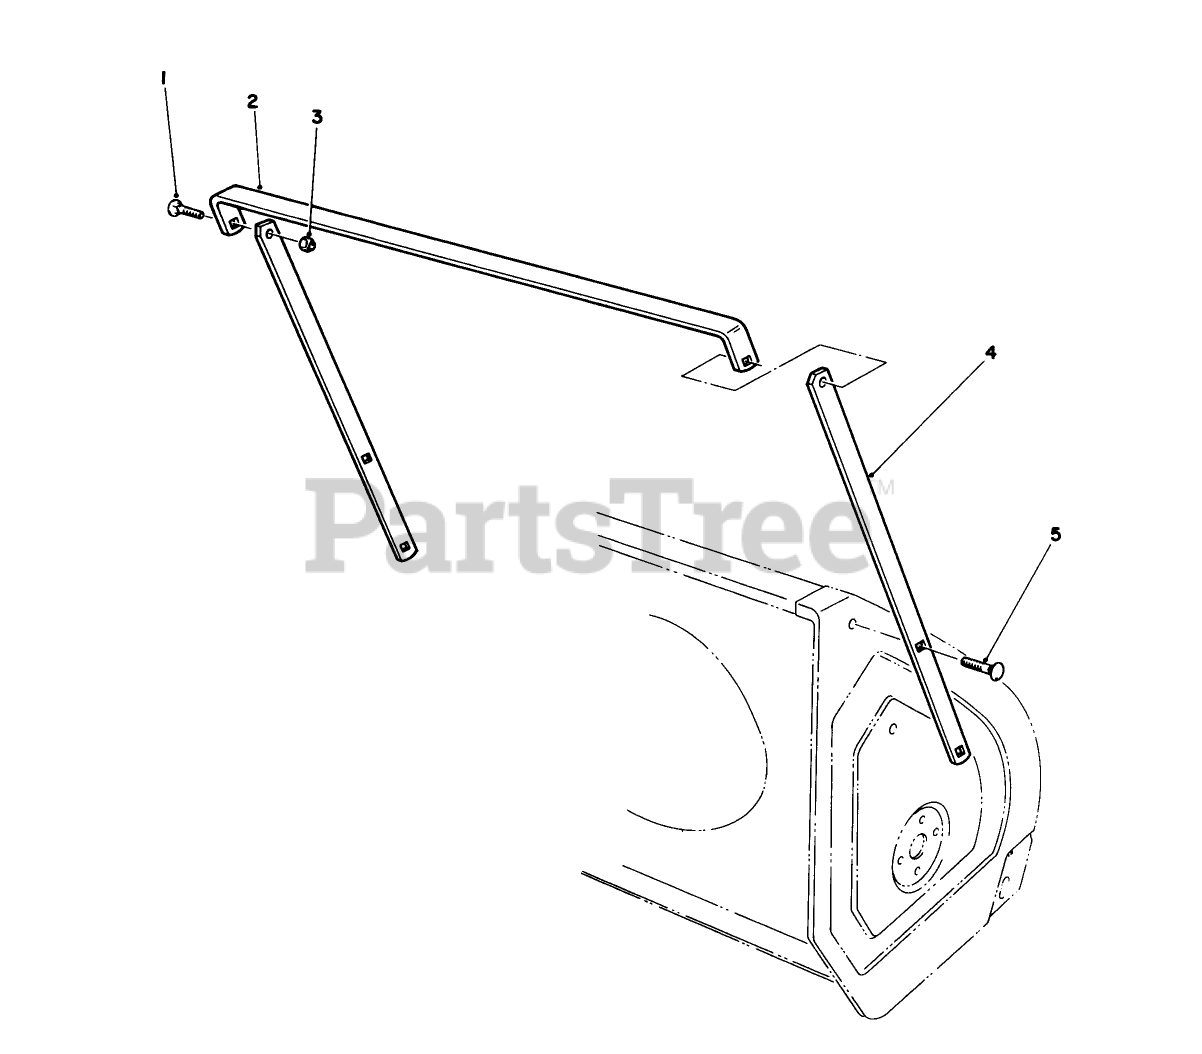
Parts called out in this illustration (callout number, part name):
1	SCREW-CARR
3	NUT-LOCK, NI
4	Breaker-Side
5	BOLT-CARR
